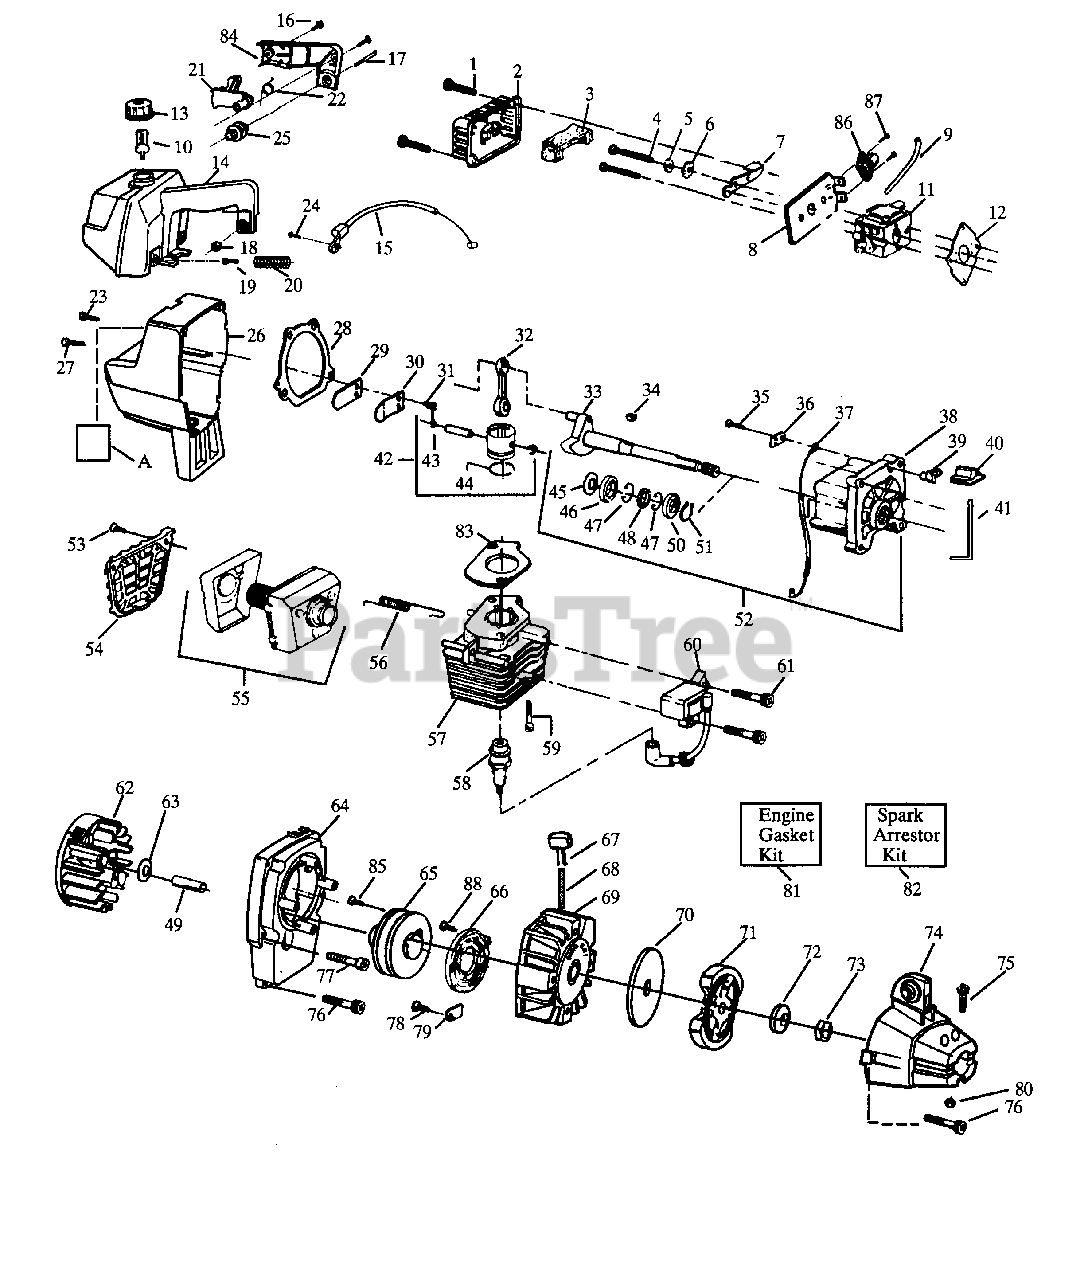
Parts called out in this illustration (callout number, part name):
2	Air Filter Cover
3	Air Filter
6	Wave Washer
7	Choke Shutter
8	MODELS GTI 18,GTI 18T,GTI 18KT
8	MODELS GTI 18KT Type 3
9	Fuel Line
9	MODEL GTI 18KT Type 2 & 3
10	Fuel Pick-up Ass'y.
11	MODELS GTI 18 & GTI 18T Type 1
11	MODELS GTI 18 & GTI 18T Type 2 & 3
12	Carburetor Gasket
13	Fuel Cap Ass'y.
14	MODELS GTI 18 & GTI 18K Type 1
14	MODELS GTI 18 & GTI 18K Type 2 & 3
15	Throttle Cable Ass'y.
16	Screw
20	Rear Isolator Spring
21	Throttle Trigger
22	Throttle Spring
23	Screw
25	Isolator
30	Reed Stop
32	Connecting Rod Ass'y.
33	Crankshaft Ass'y. See Service Ref. 1
34	Flywheel Key
36	Switch Insulator
37	Lead Wire
38	Crankcase Ass'y.
39	Switch Ramp
40	Switch Button
41	Switch Spring
42	Piston Kit
43	Piston Pin Retainer
44	Piston Ring
46	Inner Bearing
47	Retaining Ring
48	Crankshaft Seal
50	Outer Bearing
51	Crankshaft Retaining Ring
52	Crankcase & Crankshaft Ass'y.
54	Muffler Guard
55	Muffler Kit
56	Muffler Spring
57	Cylinder
57	Spark Plug
57	MODELS GTI 18, GTI 18T, GTI 18K (CJ-14)
58	MODEL GTI 18T Type 3 (RCJ-8Y)
60	Ignition Module Kit
61	Screw
62	Flywheel Ass'y.
63	Washer
64	Fan Housing
65	Starter Pulley Kit
66	Starter Spring
67	Starter Handle
68	Rope Kit
69	Pulley Housing Ass'y.
70	Clutch Washer
71	Clutch Ass'y. Kit
74	Clutch Housing
79	Pulley Retainer
81	Engine Gasket Kit (inc. 12,28,83)
82	Spark Arrestor Kit
83	Cylinder Gasket
84	Handle Cover
85	Screw-Rope Retaining
86	MODEL GTI 18T & GTI 18KT Type 2 & 3
87	MODELS GTI 18T & GTI 18KT Type 2 & 3
88	Screw-Starter Spring Type 3
A	MODELS GTI 18 & GTI 18T Type 1
A	MODEL GTI 18KT Type 2 (Not a serviceable part)
A	MODEL GTI 18KT Type 3 Decal (Not a serviceable part)
